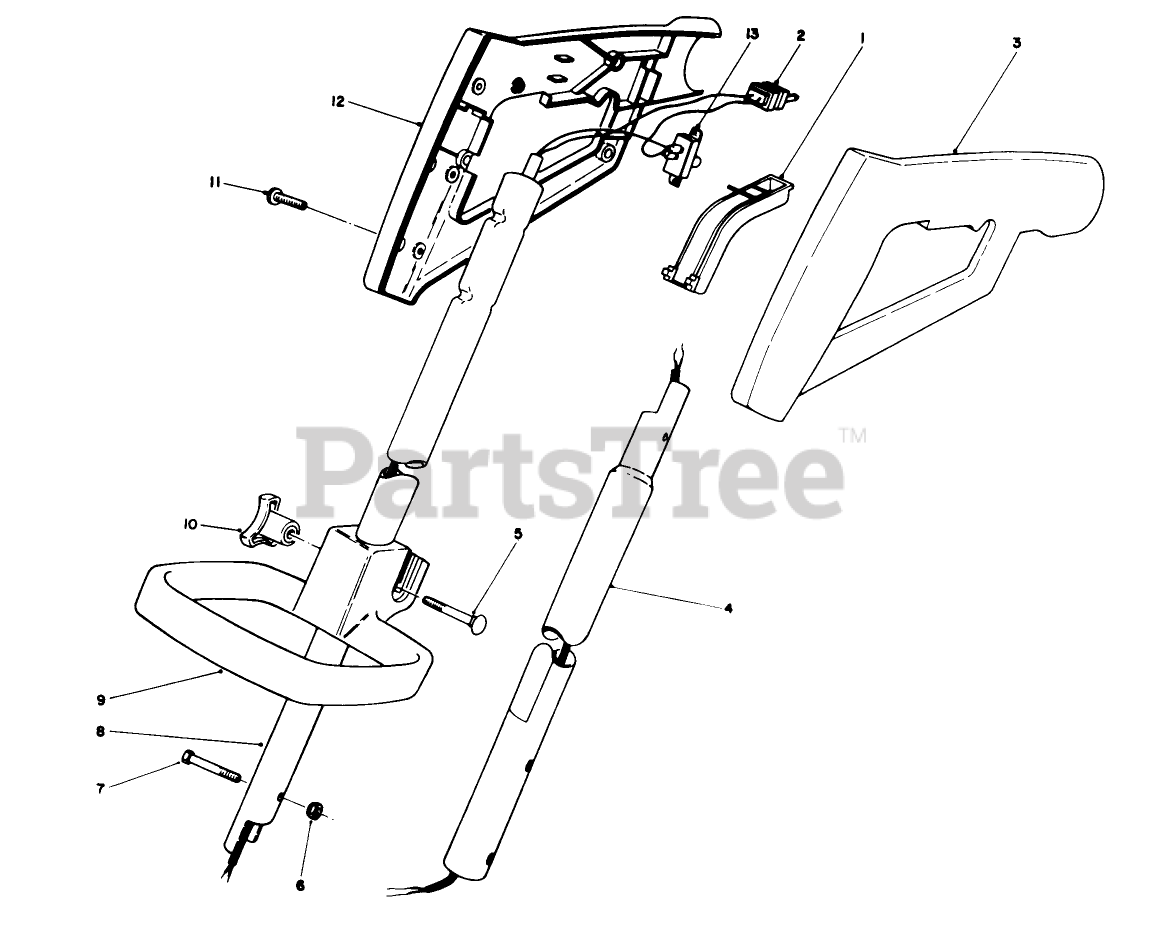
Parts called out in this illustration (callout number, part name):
1	TRIMMER - SWITCH BAR
2	WIRING HARNESS
3	HANDLE GRIP, LH
4	LOWER EXT. TUBE
5	BOLT-CARR
6	NUT-LOCK, NI
7	HEX HD MACHINE SCREW
8	UPPER TUBE
9	Handle-Adjust
10	HANDLE KNOB
11	Screw
12	HANDLE GRIP, RH
13	SWITCH
